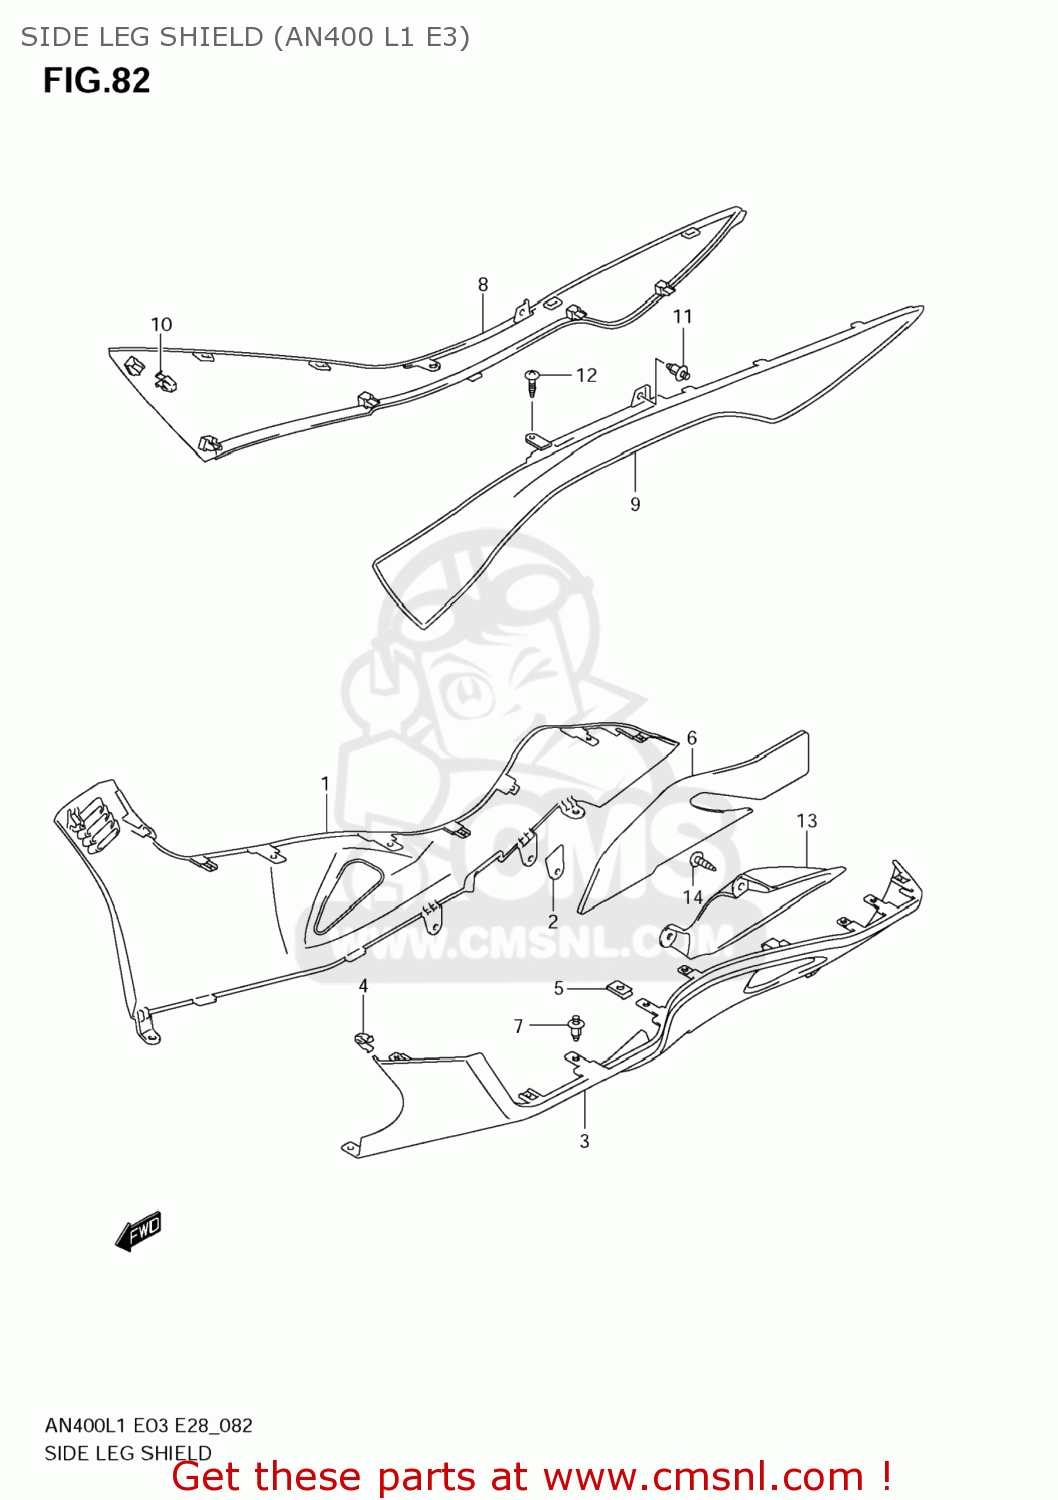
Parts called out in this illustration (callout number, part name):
1	SHIELD,LEG SIDE,R
2	SHIELD,LEG SIDE HEAT,R
3	SHIELD,LEG SIDE,L
4	CLIP
5	NUT
6	CUSHION,LEG,L
7	CLIP(BLACK)
8	COVER,LEG CTR,R
9	COVER,LEG CTR,L
10	CLIP
11	CLIP(BLACK)
12	SCREW
13	COVER,LEG SIDE,L
14	SCREW
